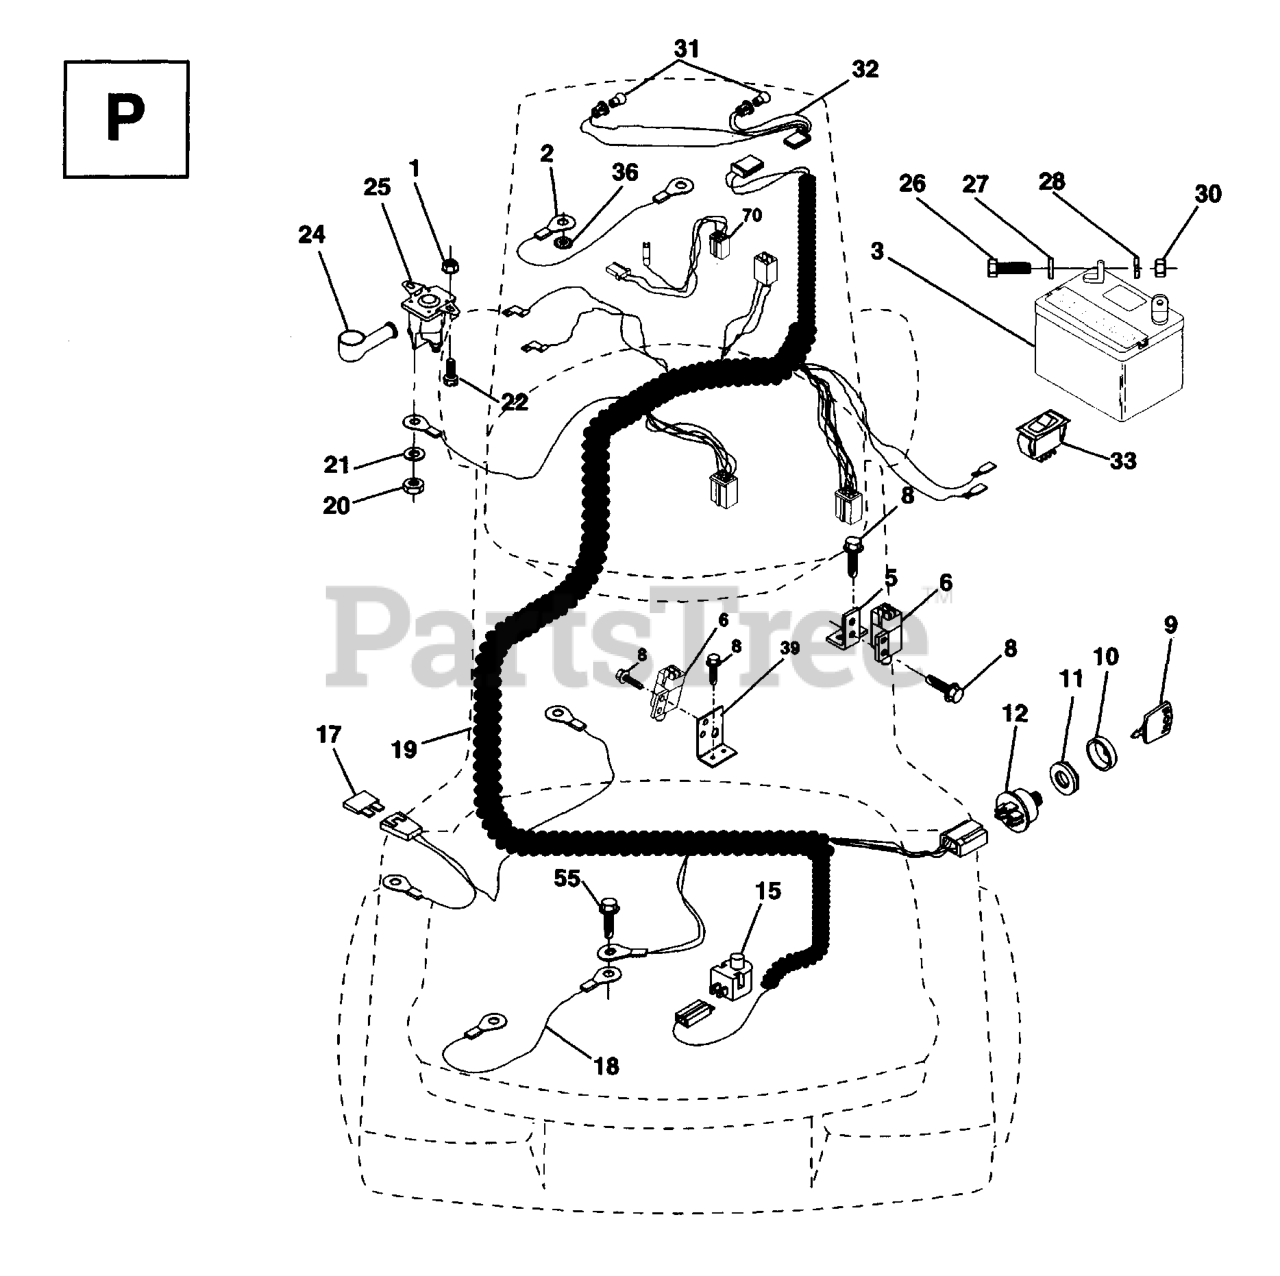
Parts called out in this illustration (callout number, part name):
1	Nut, Keps Blk Hex 1/4-20 UNC
2	CABLE.BATTERY.6GA.16"RED
3	REPL BY 532 12 38-99
5	BRACKET LT
6	SWITCH INTERLOCKT
9	KEY MLD GEN DELTA
10	COVER SWITCH KEY
11	NUT, IGNITION
12	IGNITION SWITCH
15	RP.SWITCH.PLUNGER.NC.GRAY
18	CABLE ASSY
19	HARNESS, IGN FEND
19	HARNESS IGN LR NLA
20	NUT
21	LOCKWASHER
22	BOLT
24	TERMINAL COVER
25	SOLINOID
26	BOLT.HEX.1/4.X.3/4.DICHROMATE
28	LOCKWASHER
30	NUT
32	HARNESS HEADLIGHT
36	LOCKWASHER
55	Screw 5/16-18 x 1/2 Hex, Self Tapping 5/16-18 x 1/2
70	HARNESS, ENGINE
